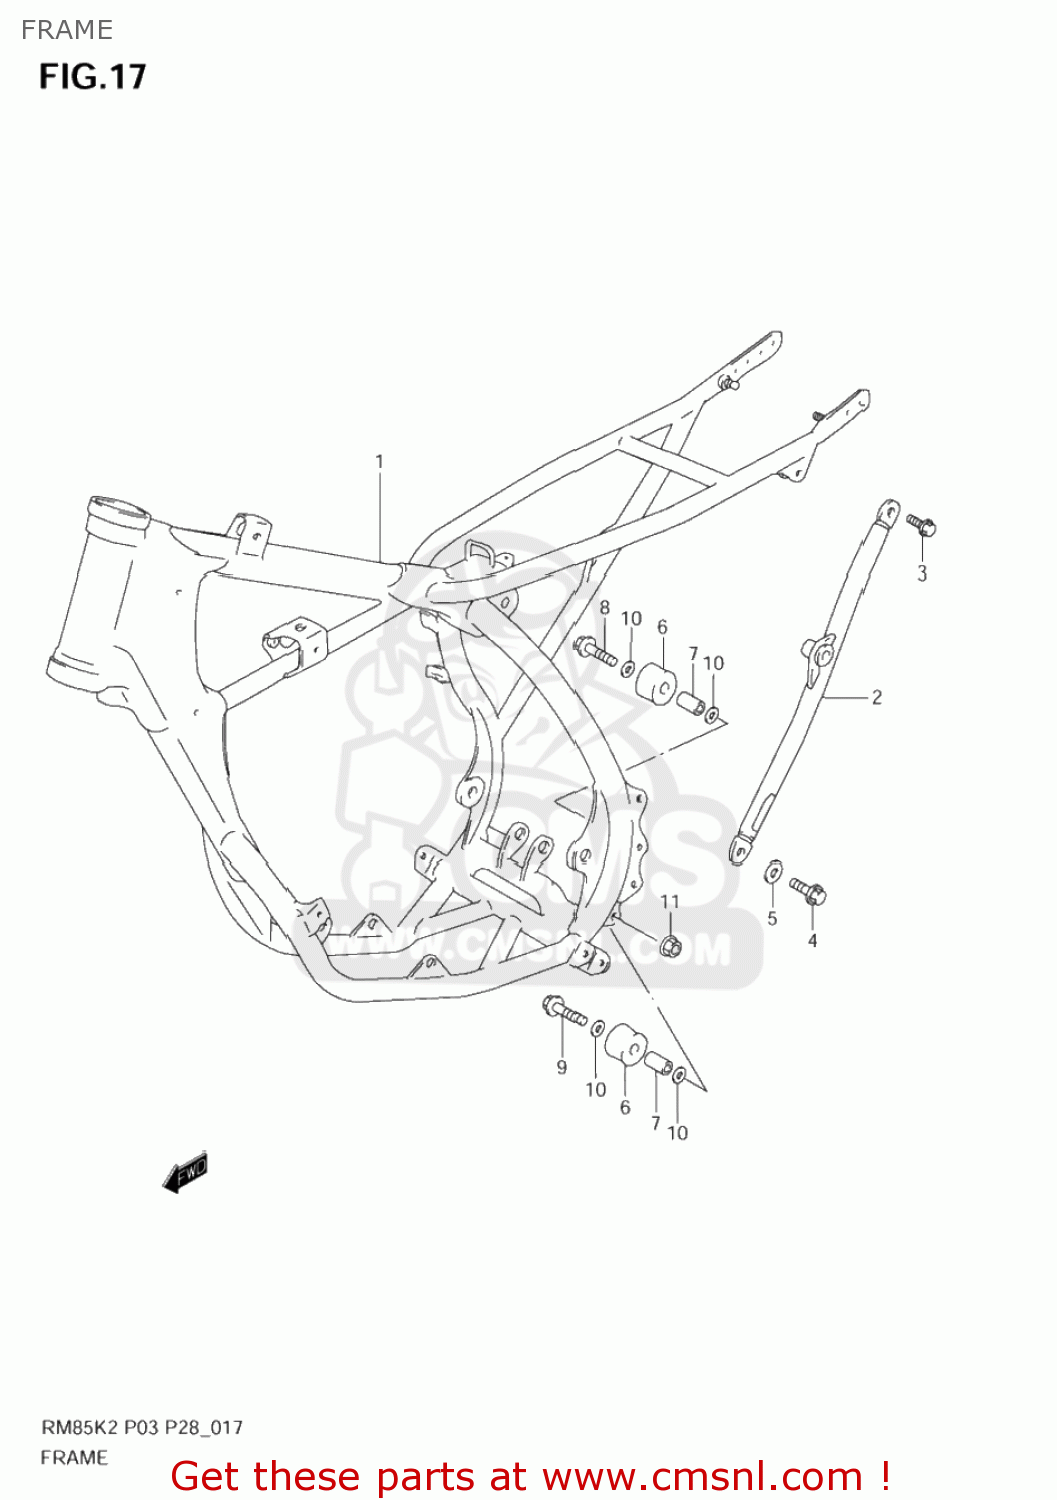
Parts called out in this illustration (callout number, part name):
1	FRAM
2	TUBE,FRAME SIDE,L(GRAY)
3	BOLT(8X22)
4	BOLT(8X16)
5	WASHER
6	ROLLER,CHAIN CONTROL
7	SPACER(8.6X12.2X25.5)
8	BOLT(8X38)
9	BOLT
10	SHIM(8X16X1)
11	NUT
